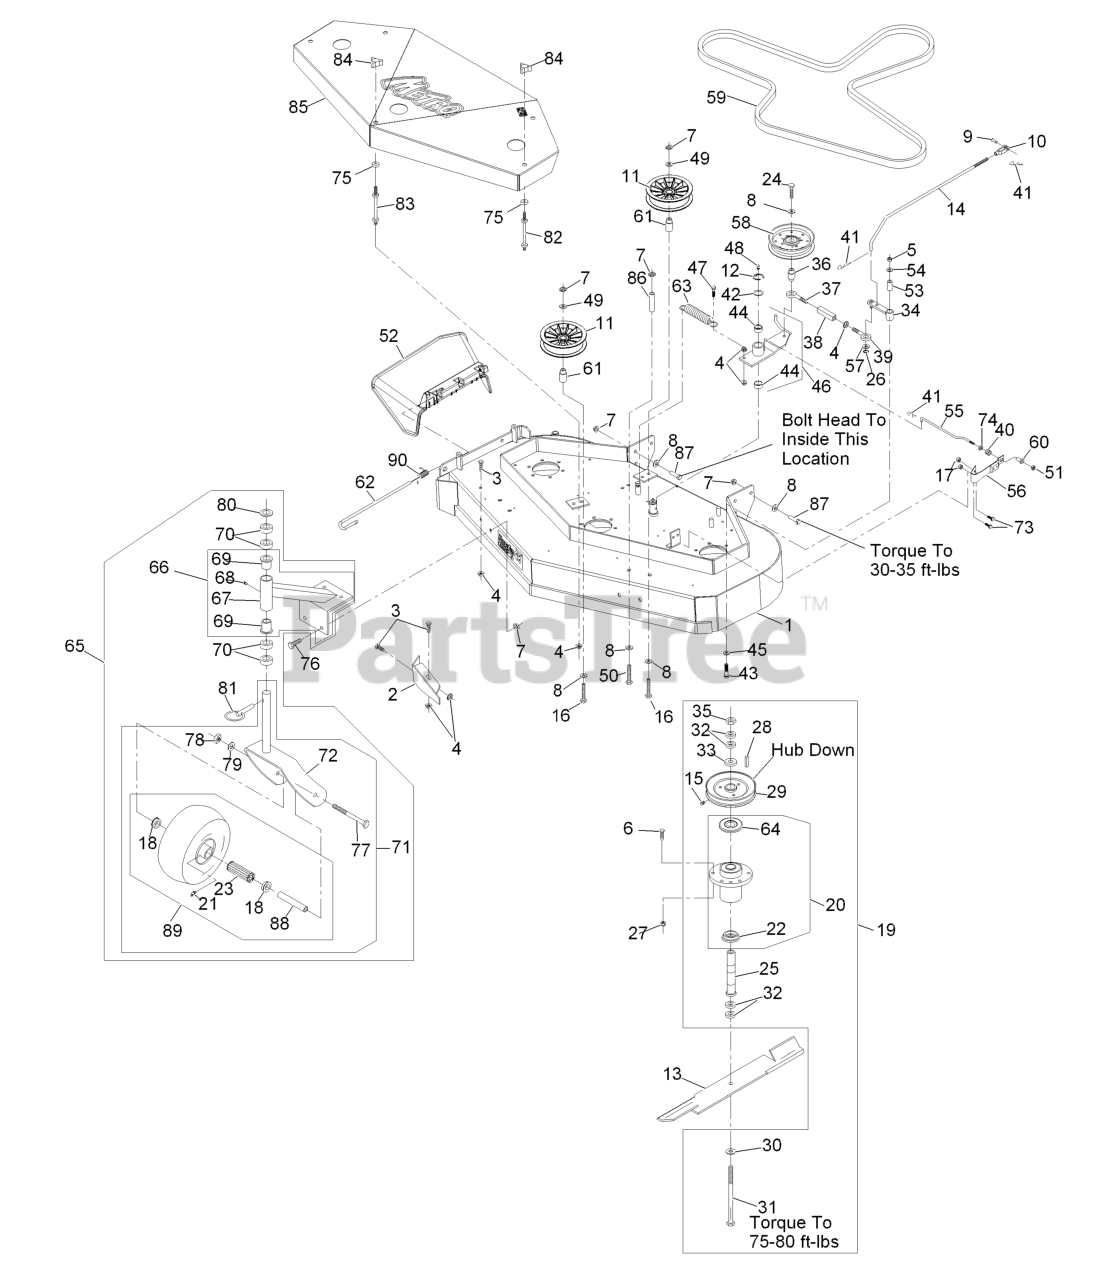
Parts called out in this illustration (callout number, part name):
2	BAFFLE-DOGLEG
3	SCREW-HH
5	NUT-LOCK, NI
6	SCREW-HH
7	NUT-HHF, WHIZ
8	WASHER-BELLEVILLE
9	PIN-CLEVIS
10	YOKE-ADJUSTABLE
11	PULLEY,IDLER 5"
12	RING-RETAINING, EXT
14	ARM-ASSIST, LINKAGE
15	SETSCREW
16	SCREW-HH
17	NUT-LOCK, NI
18	BUSHING
19	ASM, CUTTER HOUSING OUTER
20	KIT, CUTTER HOUSING
21	FITTING-GREASE
22	SPACER-GUARD, BOTTOM
23	BEARING
24	SCREW-HH
25	TUBE-SPINDLE, SHORT
26	RING-RETAINING, EXT
27	NUT-LOCK, NI
29	SHEAVE
30	WASHER-SPRING
31	SCREW-CAP, HH
33	WASHER-RETAINER, SHEAVE
34	ARM-ASSIST, 32/36
35	NUT-HEX
36	BUSHING-ENGAGEMENT
37	EYEBOLT-THREAD, LH
38	BODY-TURNBUCKLE
39	EYEBOLT-THREAD, RH
40	SPRING-COMPRESSION
41	PIN-COTTER
42	WASHER-SPINDLE
43	SCREW-HH
44	SLEEVE-BEARING
45	WASHER-SPRING
46	IDLER ARM ASM
47	SCREW-HH, SPECIAL
48	FITTING-GREASE
49	WASHER-FLAT
50	SCREW-HH
51	NUT-LOCK, NI
52	CHUTE DEFLECTOR XRK M056
53	TUBE-PIVOT
54	WASHER-FLAT
55	ROD-BRAKE
56	PAD AND SPRING ASM
57	WASHER-PLAIN
59	BELT,BLADE 48
60	SPACER-FLANGED
61	BUSHING-IDLER
62	PIN-CHUTE
63	SPRING-EXTENSION
64	GUARD-BEARING, TOP
65	ASM,CASTER/MOUNT
66	SUPPORT ASM
68	FITTING-GREASE
69	BEARING-FLANGED
70	SPACER-CASTER
71	ASM,CASTER/WHEEL
73	SCREW-HH
74	RING-PUSH ON
76	SCREW-HH
77	SCREW-HH
78	NUT-HH
79	WASHER-LOCK
80	WASHER-FLAT
82	STUD-SHIELD, BELT (SHORT)
83	STUD-SHIELD, BELT (LONG)
84	KNOB-3 PRONG
85	ASM,SHIELD W/DECALS 48 ME
87	SCREW-HH
89	KIT, SP CASTER WHEEL REPL
90	SPRING, TORSION
